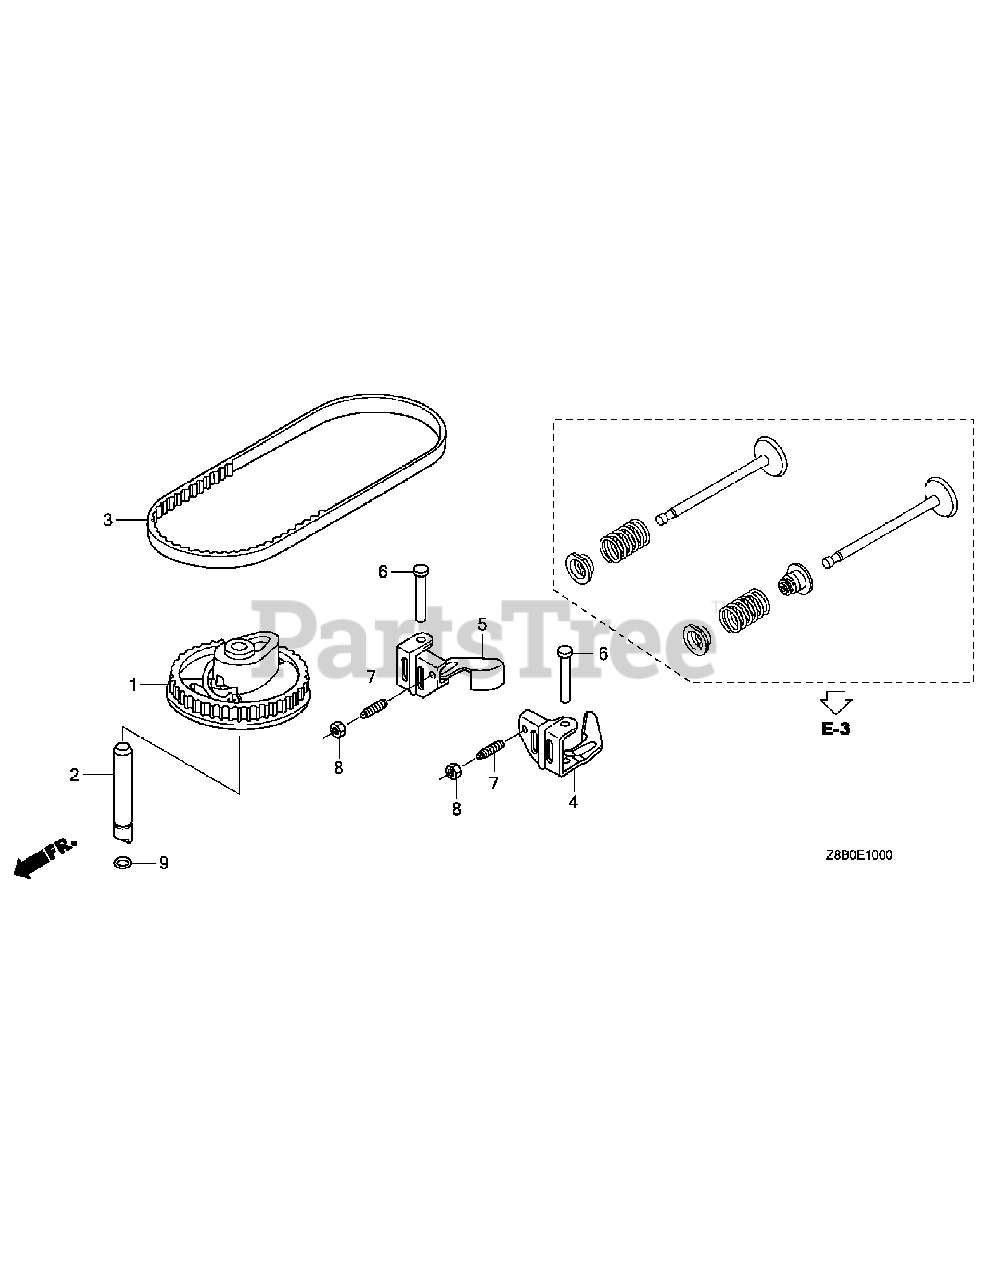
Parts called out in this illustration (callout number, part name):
1	PULLEY, CAMSHAFT
2	SHAFT, CAM PULLEY
3	BELT, TIMING (84HU7 G-200)
4	ARM, IN. VALVE ROCKER
5	PRI; ARM, EX. VALVE ROCKER
6	SHAFT, ROCKER ARM
7	SCREW, TAPPET ADJUSTING
8	NUT, TAPPET ADJUSTING
9	O-RING (6.8X1.9) (ARAI)
